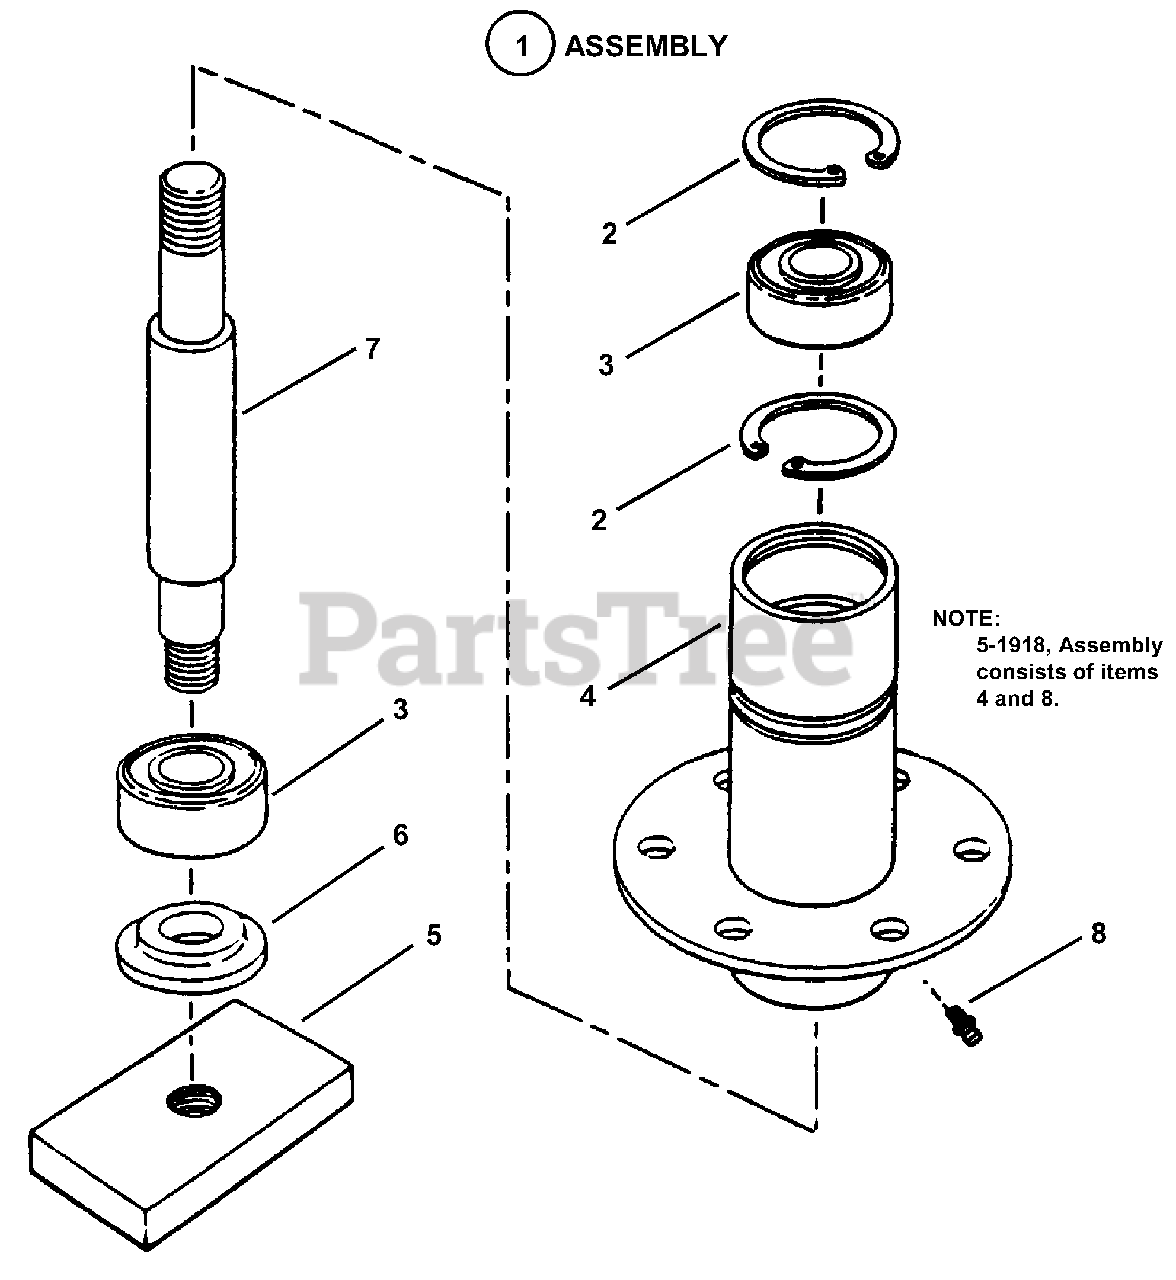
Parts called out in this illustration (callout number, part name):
1	ASSEMBLY, Spindle Housing, 42" Cutting Deck
2	RING, Retaining
3	BEARING, Spindle
4	HOUSING, Spindle (weldment) (5.1" overall length)
5	HOLDER, Blade
6	WASHER, Spindle
7	SPINDLE (6.5" overall length)
8	FITTING, Lube (Press fit for .187 hole-no ball)
51918	ASSEMBLY
